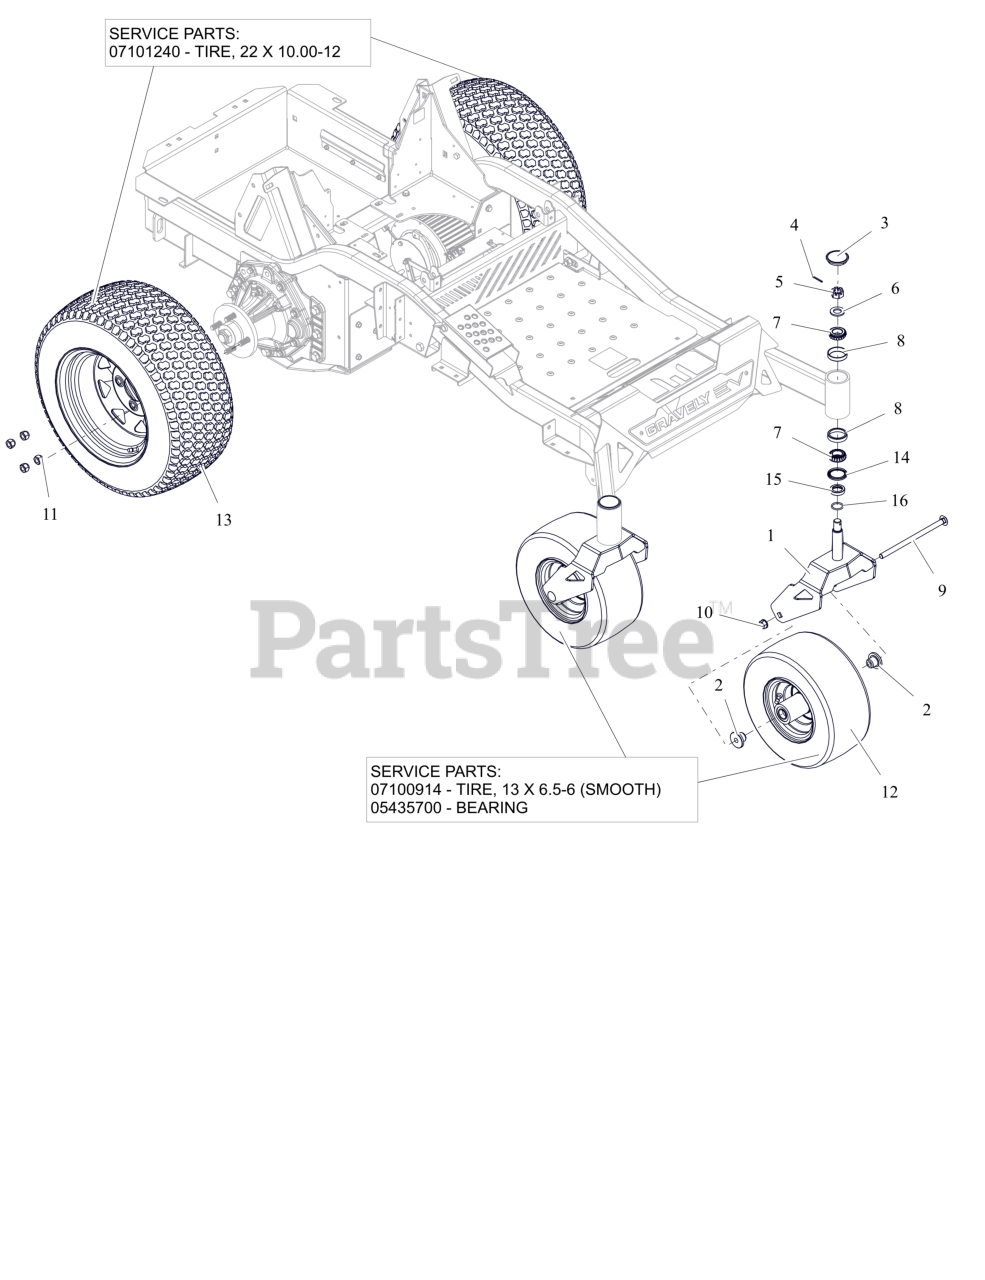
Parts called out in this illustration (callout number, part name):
1	WLDMT- CASTER FORK
2	SPACER, FRONT WHEEL
3	CAP, DUST
4	PIN,CTR.12X1.25EXTPRSQCT ZC120
5	NUT, SLOTTED .75-16
6	WSHR-FL-STL 0.812X1.469X0.134 ZCC
7	BRG-CONE 1.0X.58
8	BRG-CUP1.980X.420
9	BTL,RHSN .500-13 X 9 G5 ZCC
10	NUT-LK-CTR-FLG .500-13 GG ZCC
11	NUT, WHEEL .50-20 ZCC
12	ASM, WHL/TIRE 13X6.50-6
12	TIRE, 13X6.50-6 SMOOTH
12	BRG, 25MM ID X 52MM OD X 15MM
12	TIRE TUBE 13X6.5-6
13	ASM, WHL/TIRE 22X10.00-12 K500
13	TIRE, 22X10.00-12
13	TUBE 22,23&24X8.50/9.50/10.00/10.50/12.00-12
14	BEARING SEAL 1.5 X 2 X .18
15	SPCR, CASTER FORK (1.00)
16	O-RING 1.000X1.250X
